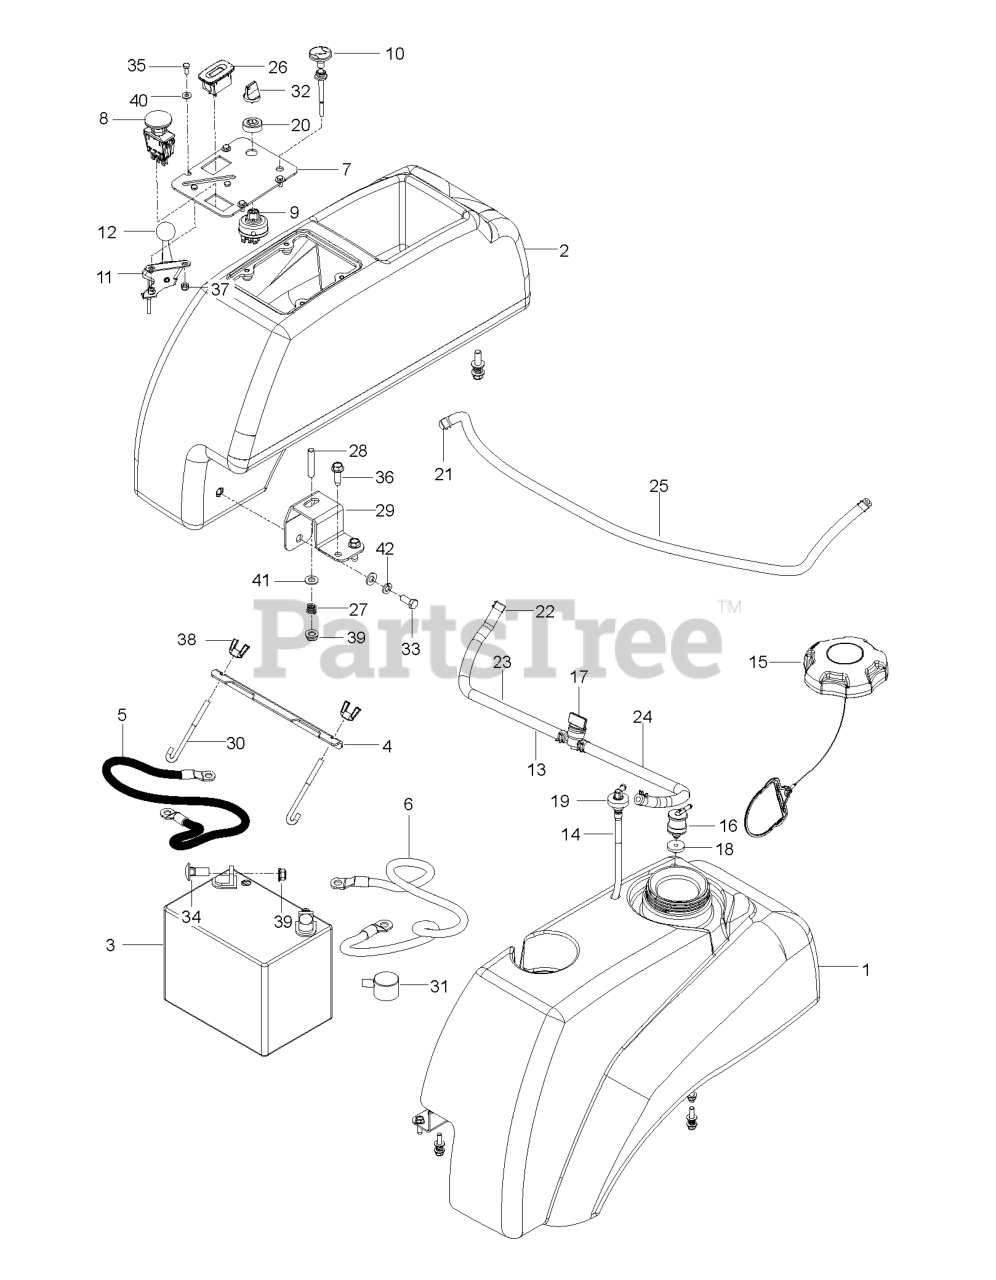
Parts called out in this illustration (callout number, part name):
1	FUEL.TANK.ASSY.LH.MZ.GRY.17
2	FENDER CONSOLE
3	BATTERY, 12 V 330 AMP
4	BRACKET.BATTERY.MOUNT.PLATED
5	CABLE.GROUND.BATT.MZ.BLACK.39"
6	CABLE.BATT.SOLENOID.MZ.RED.25"
7	PLATE.CONSOLE.BLACK
8	RP SWITCH.PTO.TERMINAL.STD.RED
9	SWITCH, IGNITION, INDAK
10	CHOKE CONTROL CABLE 57"
11	THROTTLE CONTROL W/BALL KNOB
12	KNOB.ROUND.BALL.BLACK
13	FUEL.HOSE.SHUT.OFF.ASM.10".26"
14	FITTING, FUEL
15	CAP, FUEL
16	VALVE.FUEL.CHECK
17	FUEL VALVE
18	GROMMET, CHECK VALVE
19	RUBBER GROMMET
20	CAP IGNITION NUT
21	CLAMP, HOSE
22	HOSE CLAMP
23	HOSE.1/4".LOW.PERM.FUEL.LN.10"
24	HOSE.1/4".LOW.PERM.FUEL.LN.26"
25	HOSE.3/16".VAPOR.LINE.55"LGTH
26	GUAGE.SRVCMNDR.HRMTR.
28	STUD, 5/16C
29	SUPPORT.PNT.TANK.FRONT.STAMPED
31	COVER.TERMINAL.BATTERY
32	KEY, IGNITION
33	HCS 5/16C X 3/4
34	BOLT 5/16C X 3/4" CARRIAGE
35	HCS #10-24 X 1/2
36	SCREW
37	NUT 10-24 NYLOC
38	WING NUT 1/4
39	5/16-18 NYLOC FLANGE NUT
41	WASHER
42	WASHER.LOCK.HVY.HLCL.SPR.5/16
